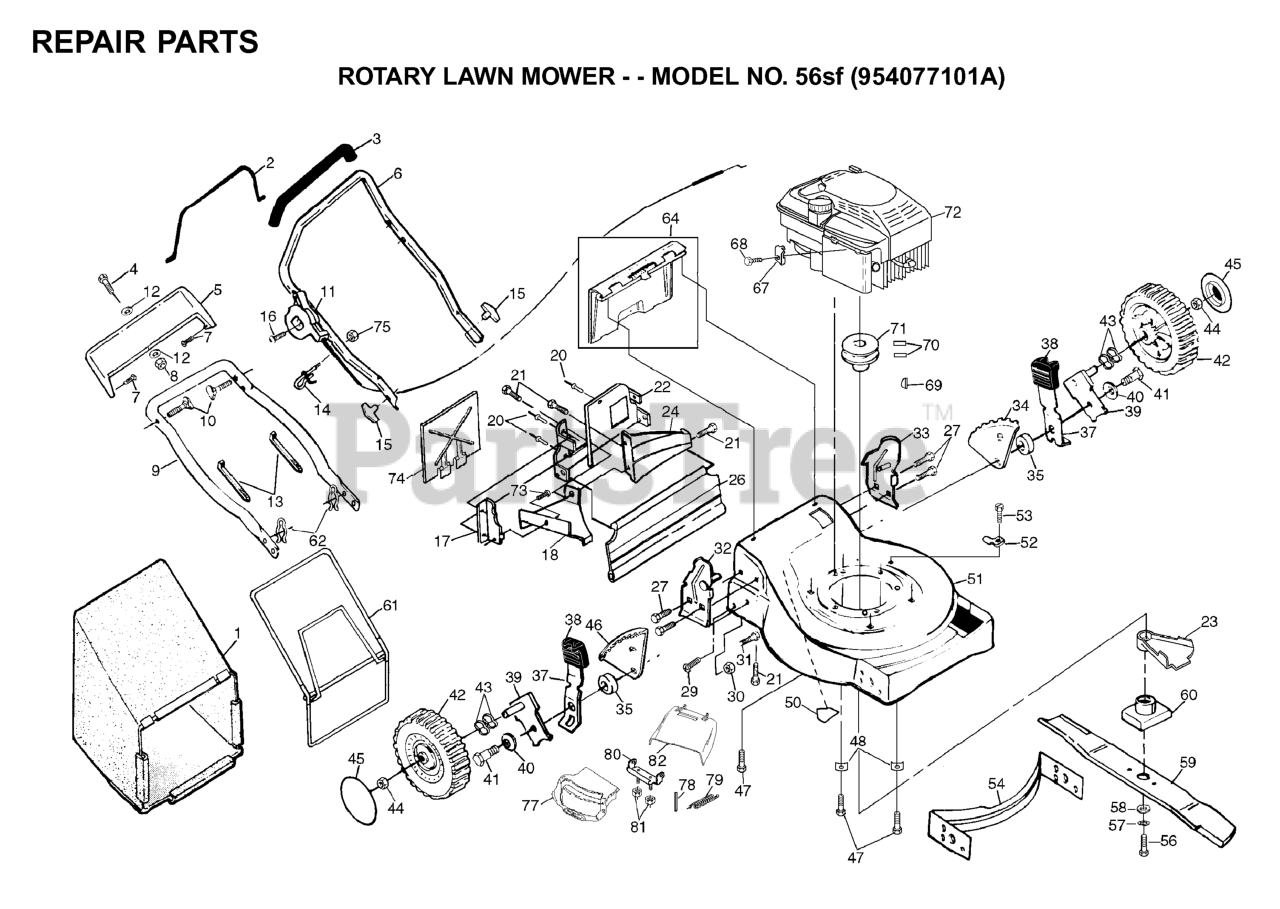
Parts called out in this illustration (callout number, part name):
1	GRASS BAG
2	CONTROL BAR
3	HANDLE GRIP
4	SCREW
5	TRIM PLATE
6	HANDLE, UPPER
8	NUT
9	HANDLE, LOWER PM
10	HANDLE BOLT
11	THROTTLE CONTROL
13	TIE GUIDE
14	ROPE GUIDE
15	HANDLE KNOB
16	SCREW 1/4-20X1.75
17	SIDE BAFFLE
18	DISCHARGE BAFFLE
20	RIVET BLIND
23	DEBRIS SHIELD
24	REAR BAFFLE
26	REAR SKIRT
27	SELF-TAPPING SCREW 5/16-18X3/4
29	HINGE SCREW
30	LOCKNUT PM
32	HANDLE BRACKET RH
33	HANDLE BRACKET LH
34	WHEEL ADJ BRKT RF-LR
35	RP SPACER HT ADJ
37	SELECTOR SPRING
38	SELECTOR KNOB
39	AXLE ARM
40	WASHER.BELLEVILLE (3 2 LB)
41	BOLT
42	WHL & TIRE ASSEMBLY
43	WAVE WASHER
44	HEX FLANGE LOCKNT
46	WHEEL ADJ BRKT RR-LF
47	BOLT 3/8-16X1-1/8
48	WASHER.ENGINE.BZP
50	DECAL HYT
52	GUIDE CLIP PM
53	TAPPING SCREW
54	FRONT BAFFLE
56	SCREW, HEX HD 3/8-24 X 1-3/8
57	LOCKWASHER
58	WASHER,HARDEN
60	BLADE ADAPTOR
61	CATCHER.FRAME.WALK
62	HAIRPIN COTTER
64	REAR DOOR ASSEMBLY
68	SCREW.HEX.HEAD.WASHER.10-16
69	HI PRO KEY PM WSL
71	ENGINE.PULLEY.FWG
73	SCREW.HXTAP.10-24
74	MULCHER PLATE
75	NUT
78	ROD.HINGE.COMBI-C
80	BRACKET.HINGE ASM.W/FIN
81	NUT
